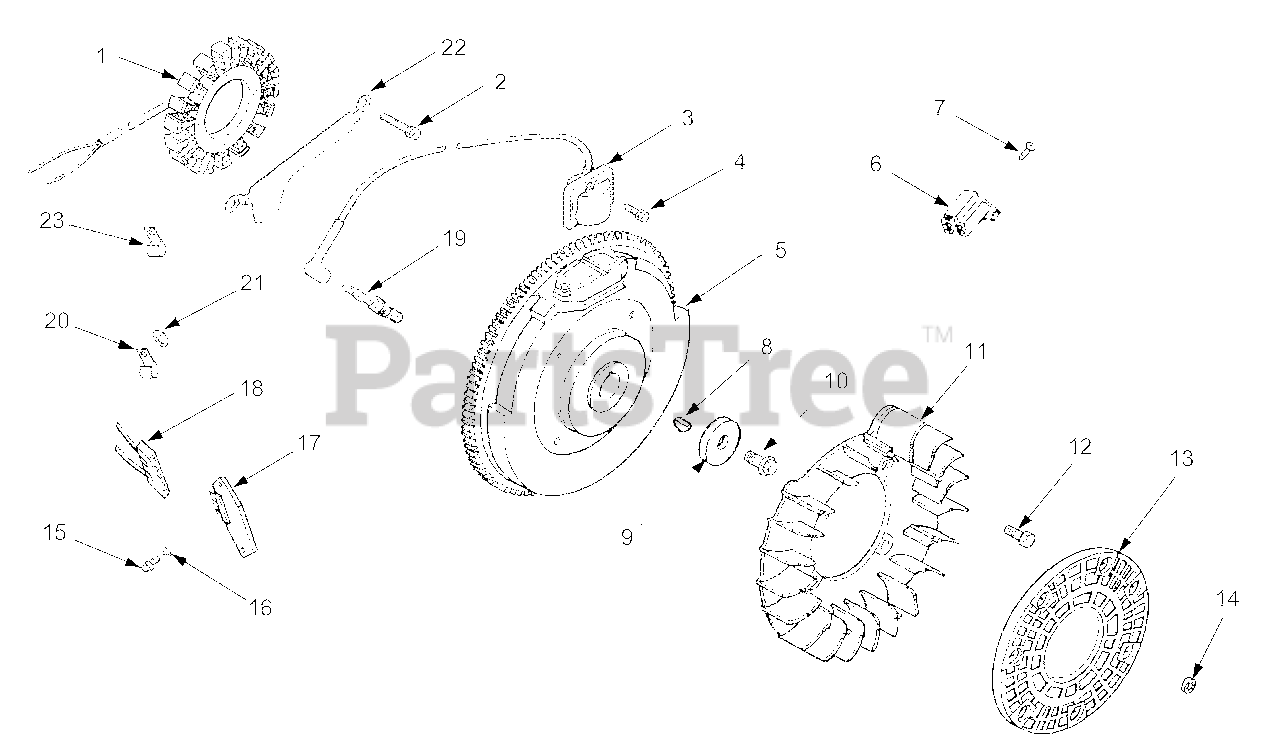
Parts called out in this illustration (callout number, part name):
1	Stator Kit, 15 Amp
2	Screw, Stator Mtg. M5 x .8 x 25
3	Module, Ignition
4	Screw, Module M5 x .8 x 20
5	Flywheel Assembly
7	Screw, Hex Sems #10-16 x 1/2
9	Washer, Flywheel Mtg. Screw
10	Screw, Flywheel Mtg, M10x1.5 x 46
11	Fan
12	Bolt, Shoulder
13	Screen, Grass
14	Retainer
15	Screw Phillips Hd., #11-16 x .875
16	Washer, Plain
17	Regulator - Rectifier
18	Connector, Regulator-Rectifier
19	Spark Plug
20	Clip, Cable
21	Washer, Plain 1/4"
22	Bracket, Stator Wire
